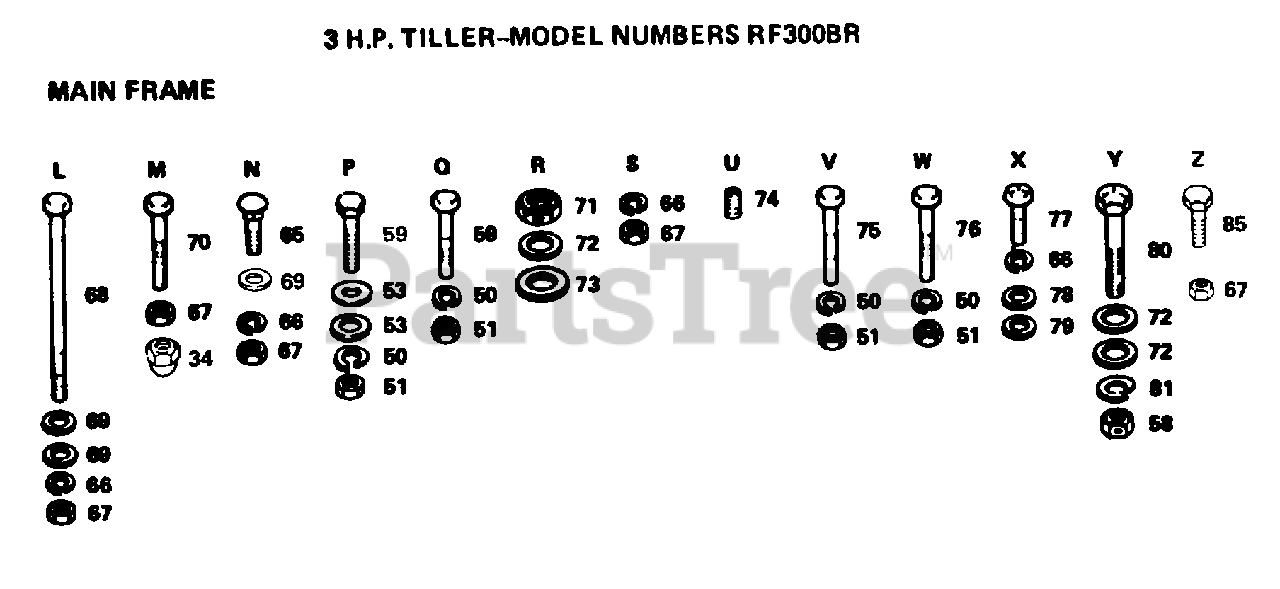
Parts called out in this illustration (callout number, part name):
34	NUT-CAP TI
50	LOCKWASHER
51	NUT.HEX.5/16-18
53	WASHER
58	GRIPCO NUT
65	BOLT
66	LOCKWASHER
69	WASHER
70	BOLT
72	WASHER
75	BOLT.HEX.5/16-1.5
77	BOLT
78	WASHER
79	WASHER
80	BOLT.3/8-24X3.75
81	LOCKWASHER
